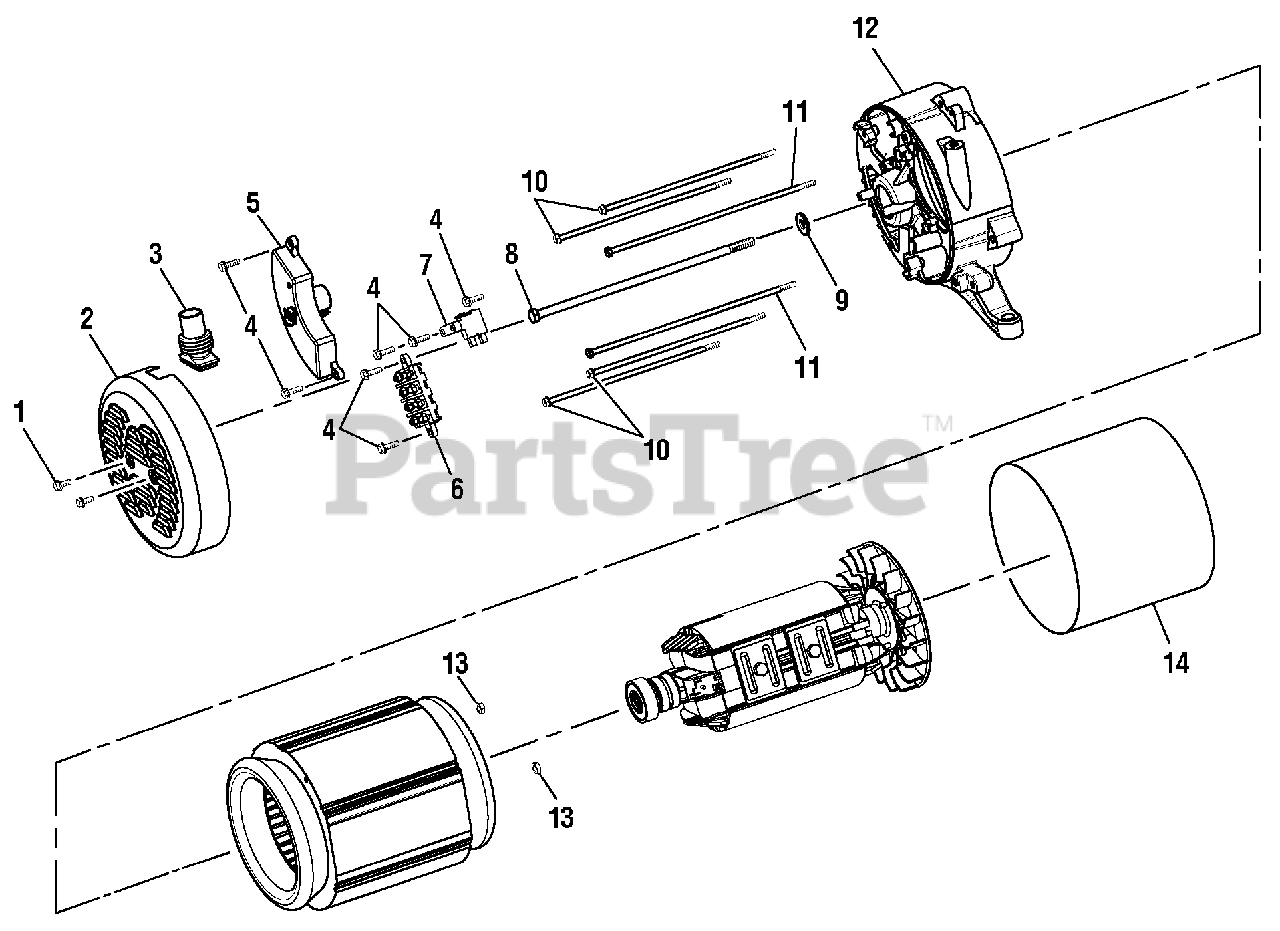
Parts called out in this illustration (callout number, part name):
1	Bolt (M5 x 12 mm, Hex Hd.)
2	Brush Cover
3	Rubber Boot
4	Bolt (M5 x 16 mm, Hex Hd.)
5	Automatic Voltage Regulator
6	Terminal Block
7	Brush Assembly Kit
8	Rotor Bolt
9	Washer (5/16 in.)
10	Stator Bolt
11	Bolt (M5)
12	Bearing Housing
13	Hex Nut (M5)
14	Generator Head Cover
